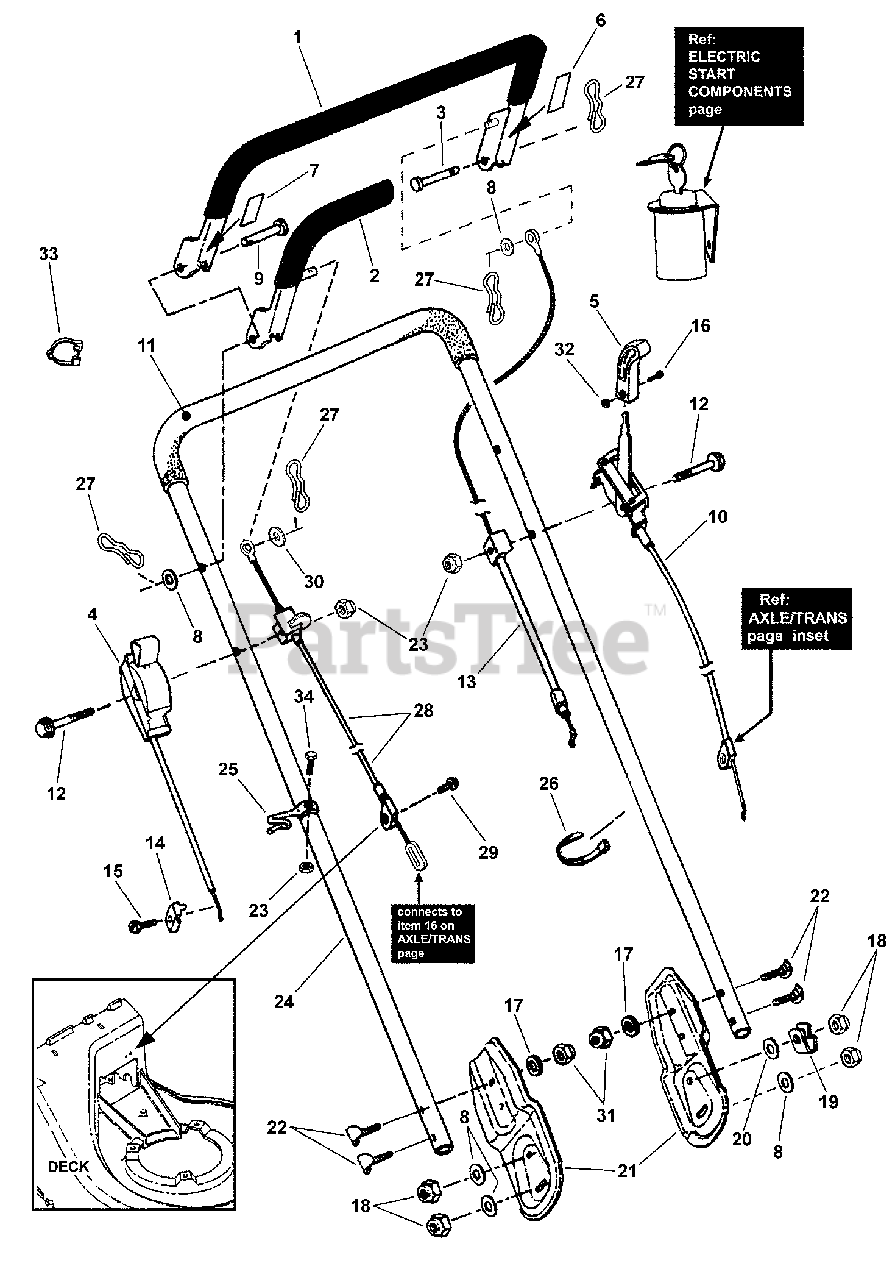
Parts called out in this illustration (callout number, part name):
1	CONTROL, Blade (ELP21502KWV)
1	CONTROL, Blade (ELP21602 & ELP21602E)
2	WELDMENT, Ground Speed Control (Coated)
3	PIN, 5/16 x 1-7/16" Clevis
4	CONTROL, Throttle (+49.8/1.41") (ELP216752BV)
4	CONTROL, Throttle (+49.8/2.62") (ELP21702BV)
5	KNOB, Engine Speed & Ground Speed Control
6	DECAL, (OPC) Operator Presence Control
7	DECAL, Ground Drive, (Cast Al Comm)
8	WASHER, 5/16" Flat
9	PIN, 5/16 x 1-3/4" Clevis
10	CONTROL, Ground Speed (+56/1.85")
11	GRIP, Foam (7/8" I.D. x 21-1/2" long)
12	SCREW, 1/4-20 x 2-3/4" Hex Head Cap, GR 5
13	*CABLE ASSEMBLY, Blade Control (49.09" long)
13	*CABLE ASSEMBLY, Blade Control (51.39" long)
14	CLAMP, Engine Speed (3-Speed Control)
15	SCREW, #10-32 x 5/8" Slotted Hex Head, Self-Tap
16	SCREW, #8-32 x 3/8" Pan Head Cross Recess
17	WASHER, 5/16" Internal Tooth Lock
18	NUT, 5/16-18 Hex Nyloc
19	CLAMP, Double Tube
20	RETAINER, 5/16" Bolt (Black)
21	BRACKET, Handle (Black)
21	BRACKET, Handle (Yellow Zinc Chromate)
22	BOLT, 5/16-18 x 1-1/2" Curved Head Carriage, GR 2
23	NUT, 1/4-20 Hex Nyloc
24	HANDLE, Upper
25	GUIDE, Pull Rope
26	TIE, Wire 1.29" long (Black)
27	PIN, Bow-Tie Locking Cotter
28	CABLE, Traction (Adjustable) (51.20/6.38")
29	SCREW, #10-24 x 5/8" Hex Washer Self-Tap
30	WASHER, 3/16" Flat
31	NUT, 5/16-18 Hex Nyloc
32	NUT, #8-32 Hex
33	CLAMP, 7/8" Double Cable
34	SCREW, 1/4-20 x 1-1/2" Hex Head Cap, GR 5
